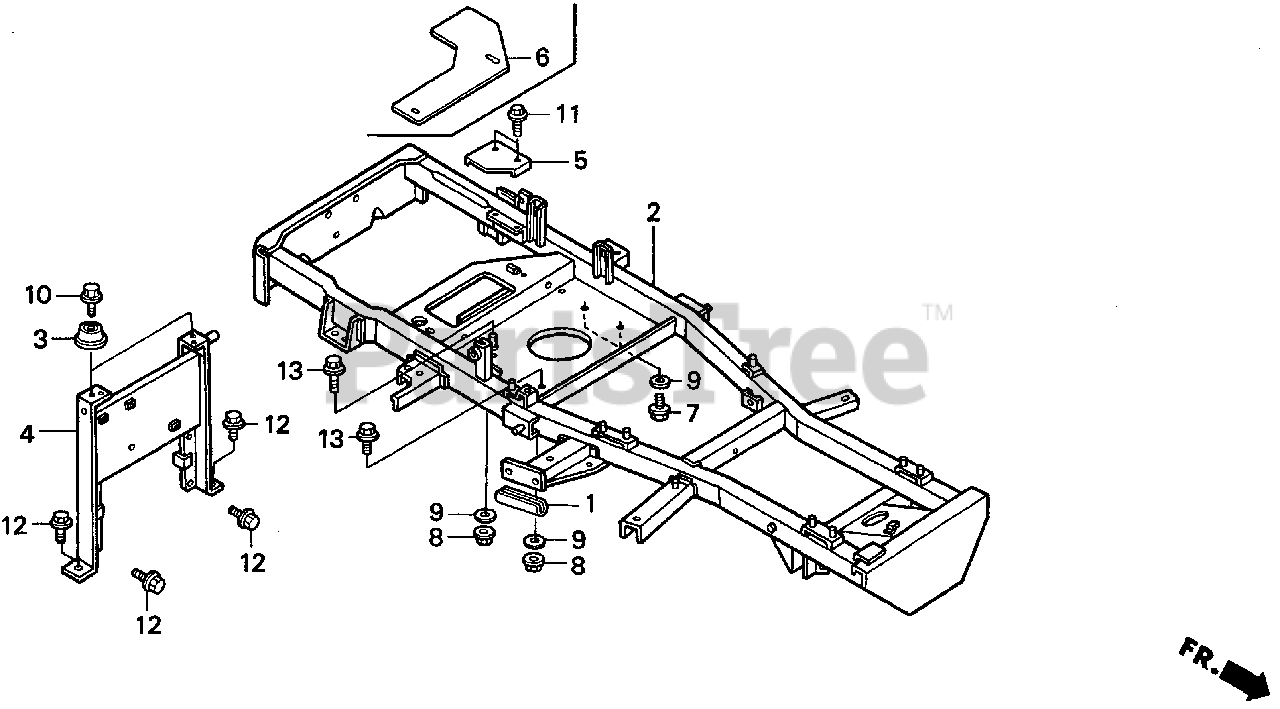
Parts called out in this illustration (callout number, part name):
1	TRIM, FUEL TANK (SOURCE: VINTAGE PARTS INC.)
3	RUBBER (LOWER) Use from Frame SN 1008046.
4	FRAME, SEAT SUPPORT
5	COVER, PRIMARY BELT
6	COVER, PRIMARY BELT
7	BOLT, FLANGE (5/16"X22)
8	NUT, FLANGE (8MM)
9	WASHER, PLAIN (8MM)
10	BOLT, FLANGE (6X12) Use from Engine SN 2086984.
11	BOLT, FLANGE (8X16)
12	BOLT, FLANGE (8X16)
13	BOLT, FLANGE (8X35)
